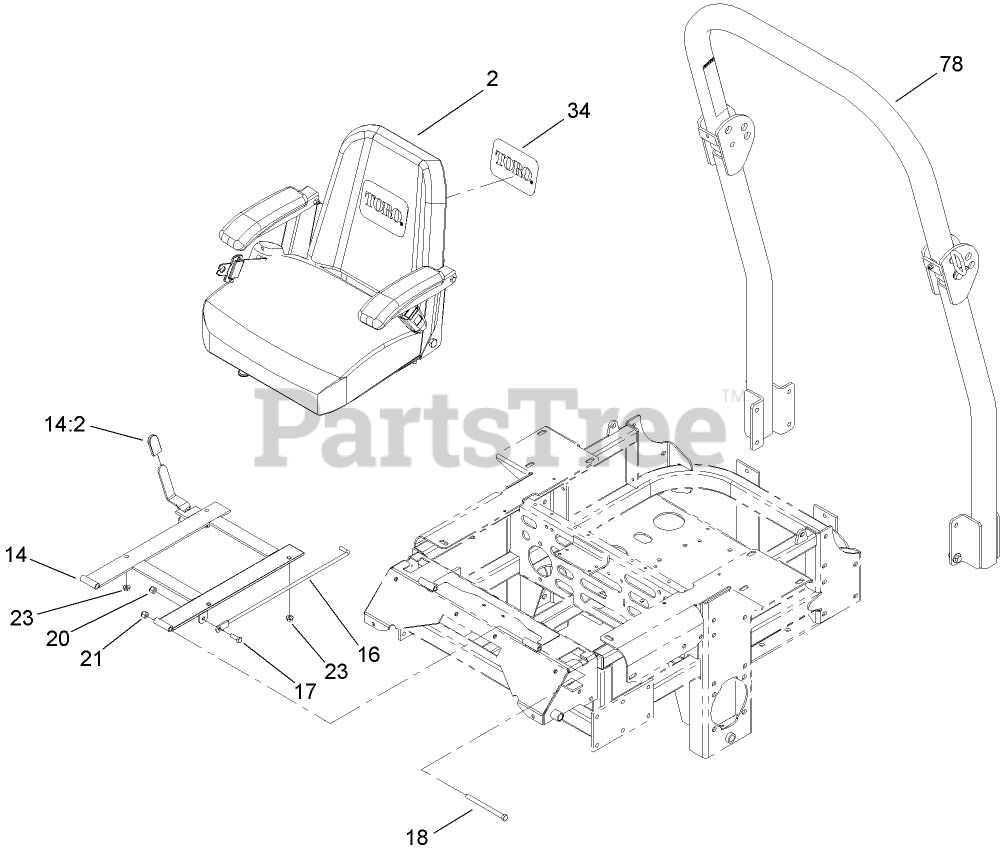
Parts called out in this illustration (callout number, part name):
2	SEAT ASM
14	SEAT FRAME AND LATCH ASM
14:2	GRIP-LEVER
16	ROD-HOLDUP, SEAT
17	SCREW-HH
18	SCREW-HH
20	NUT-LOCK, NI
21	NUT-LOCK, NI
23	NUT-HF
34	DECAL
78	ROPS ASM
